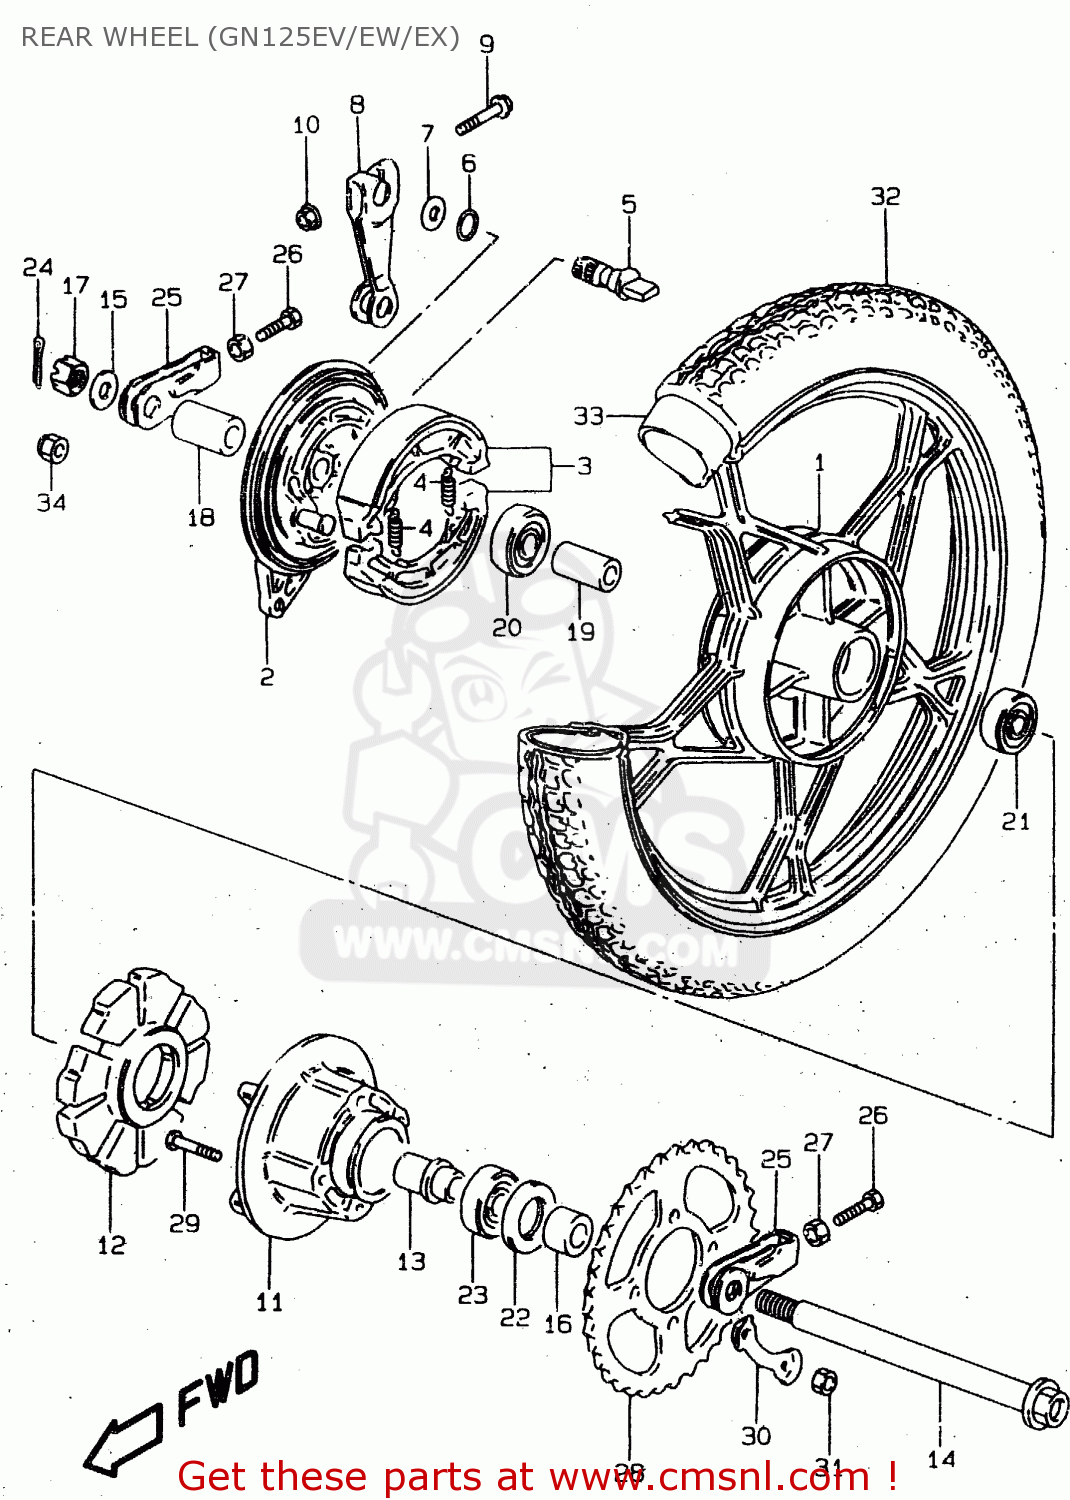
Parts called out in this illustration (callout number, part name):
1	WHEEL,RR(2.15X10)
2	PANEL,RR BRAKE ANCHOR
3	SHOE SET,BRAKE (NAS)
4	SPRING(L:34)
5	CAM,BRAKE
6	O RING(D:2.5,ID:13.8)
7	WASHER(14.5X22X1.6)
8	LEVER,RR BRAKE CAM
9	BOLT
10	NUT
11	DRUM,RR SPROCKET MOUNTING
12	ABSORBER,RR HUB SHOCK
13	RETAINER,RR SPROCKET DRUM
14	AXLE,RR
15	WASHER
16	SPACER(15X28X19)
17	NUT
18	SPACER(15.2X26X33)
19	SPACER(15.3X21.7X63)
20	BEARING
21	BEARING
22	SEAL,OIL(28X47X7)
23	BEARING(20X47X14)
24	COTTER PIN
25	ADJUSTER,CHAIN
26	BOLT(8X50)
27	NUT
28	SPROCKET,RR(NT:42)
29	BOLT
30	WASHER
31	NUT
32	TIRE,RR(3.50-16 4PR)
33	TUBE
34	NUT
